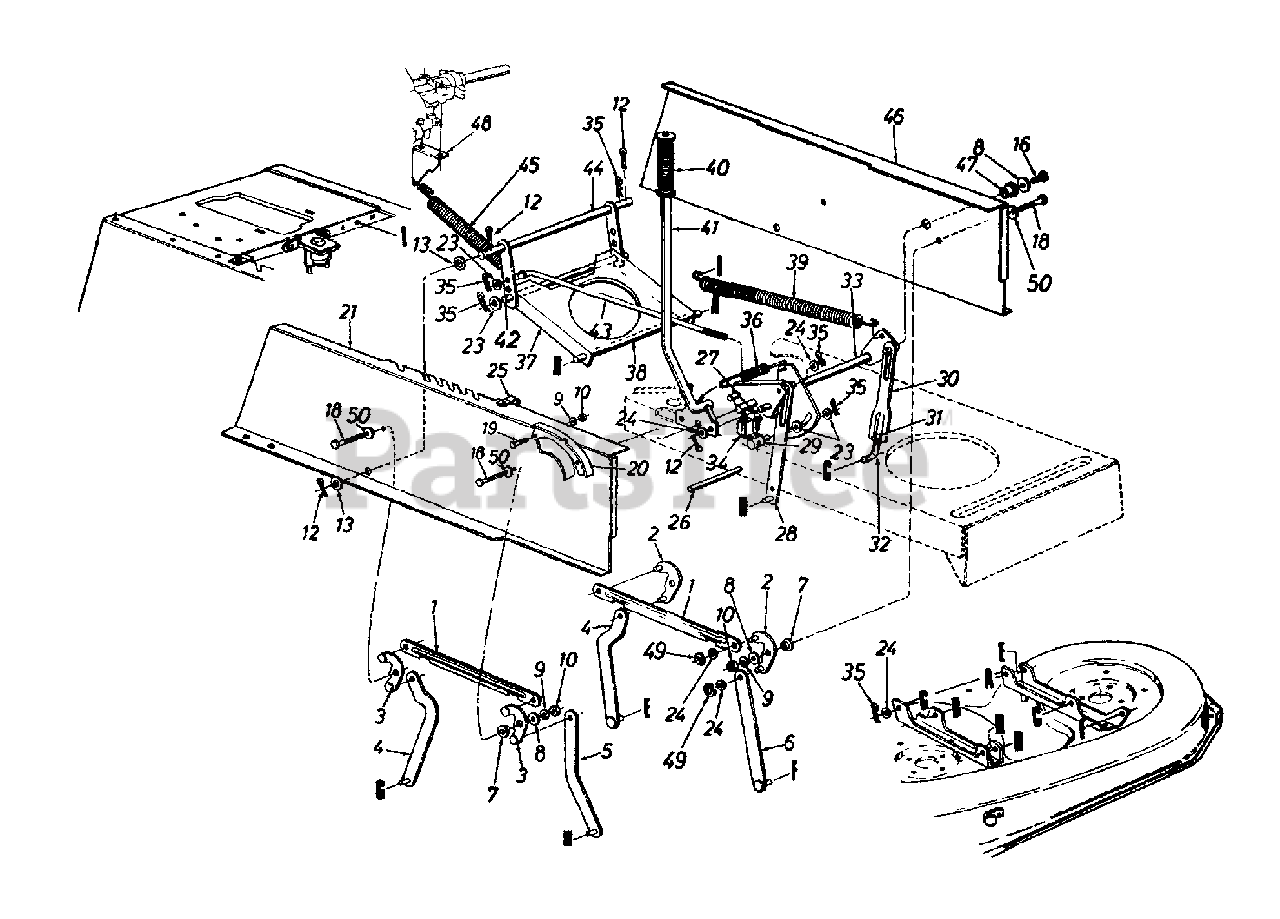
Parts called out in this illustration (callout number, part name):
3	Pivot Link Ass'y.- R.H.
7	Shld. Spacer .318" I.D.
8	Fl-Wash. .344" I.D. x .62" O.D.
9	L-Wash. 5/16" I.D.
10	Hex Nut 5/16-18 Thd. (Gr. 5)
12	Cotter Pin 1/8" Dia.
13	Fl-Wash. .635" I.D. x 1.0" O.D.
16	Hex Wash. TT-Tap Scr. 5/16-18 x .75" Lg.
18	Hex Wash. Hd. Scr. 5/16-18 x .875" Lg.
19	Hex Bolt 5/16-18 x .75" Lg.
24	Fl-Wash. .531" I.D. x .93" O.D.
26	Running Board Rod
27	Hex Wash. Hd. Tap Scr.
31	Hex Nut 1/2-20 Thd. (Gr. 5)
32	Lift Link Adjuster
33	Lift Shaft Ass'y.
34	Safety Switch (Deck)
35	Inter. Cotter Pin 3/8" Dia.
36	Extension Spring
39	Extension Spring
40	Grip (Lift Handle)
43	Disengagement Rod
49	"E"-Ring
50	Bell-Wash. .325" I.D.
97675A-0637	LIFT HANDLE ASSY POWDER BLACK - POWDER BLACK (0637)
97675A-0638	LIFT HANDLE ASSY POWDER BLACK - MTD/TROY-BILT RED (0638)
97675A-0648	LIFT HANDLE ASSY POWDER BLACK - TECH GRAY (0648)
97675A-0665	LIFT HANDLE ASSY POWDER BLACK - YARDMAN GREEN (0665)
